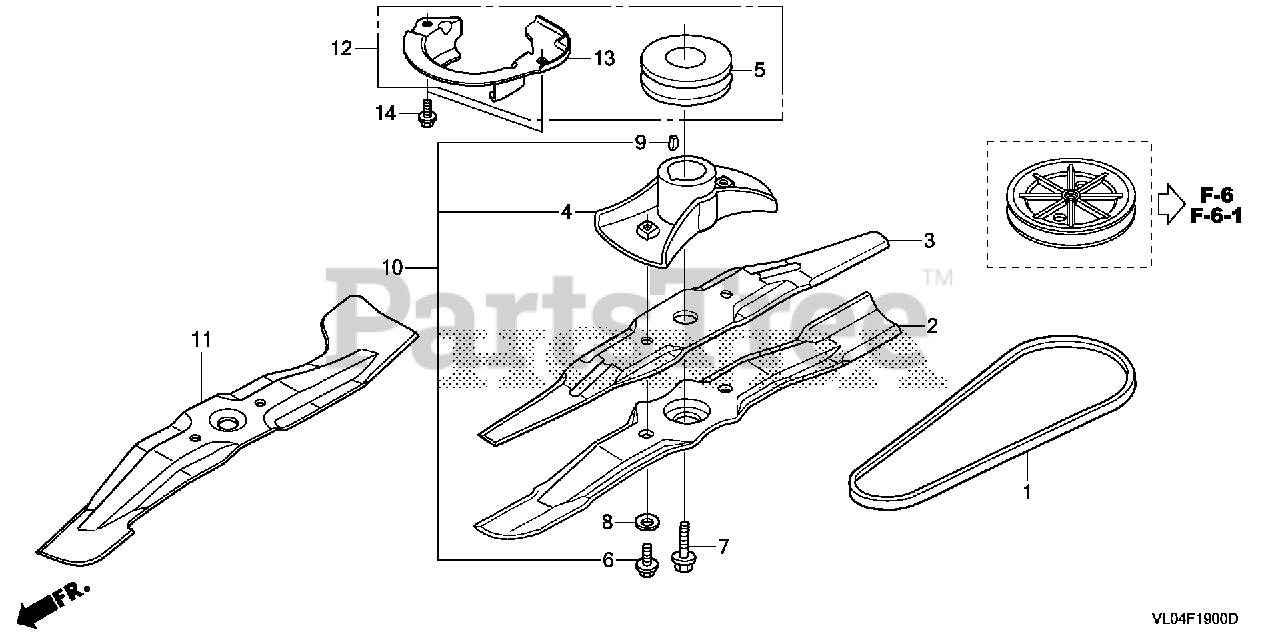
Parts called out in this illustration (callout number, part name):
1	V-BELT
3	BLADE, ROTARY (UPPER)
4	HOLDER, BLADE
5	PULLEY, DRIVE
6	BOLT, HEX. (10X25)
7	BOLT, FLANGE (3/8-24X1")
8	WASHER, SPRING (10MM)
9	KEY, WOODRUFF (3/16X5/8)
11	BLADE, ROTARY
13	GUIDE, ENGINE BELT
14	BOLT, FLANGE (6X14)
